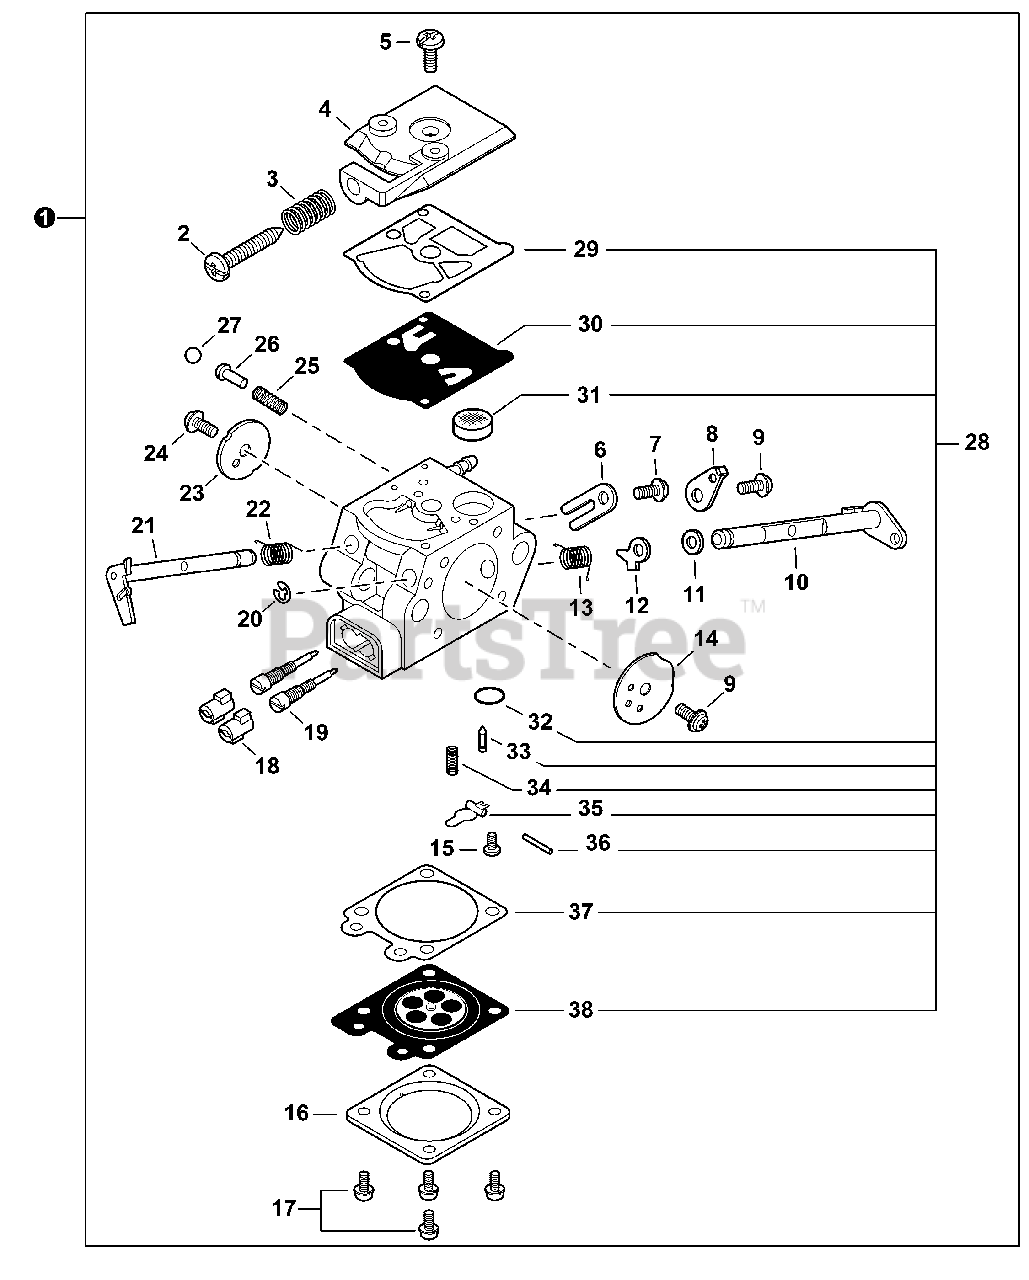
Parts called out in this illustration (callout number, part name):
1	CARBURETOR - WT-1089
2	SCREW, IDLE ADJUST
3	SPRING, IDLE ADJUST
4	COVER, PUMP
6	CLIP, THROTTLE SHAFT
8	LEVER, THROTTLE
10	SHAFT, CHOKE
12	LEVER, FAST IDLE
14	VALVE, CHOKE
15	SCREW, METERING LEVER PIN
16	COVER, METERING DIAPHRAGM
18	CAP, LIMITER
19	NEEDLE, MIXTURE
21	SHAFT ASSY, THROTTLE
22	SPRING, THROTTLE RETURN
23	VALVE, THROTTLE
25	SPRING, START VALVE
26	PISTON ASSY
28	REPAIR KIT, CARBURETOR
29	GASKET, PUMP
30	DIAPHRAGM, PUMP
31	SCREEN, FUEL INLET
32	PLUG, WELCH
33	VALVE, INLET NEEDLE
34	SPRING, METERING LEVER
35	LEVER, METERING
36	PIN, METERING LEVER
37	GASKET, METERING DIAPHRAGM
38	DIAPHRAGM, METERING
